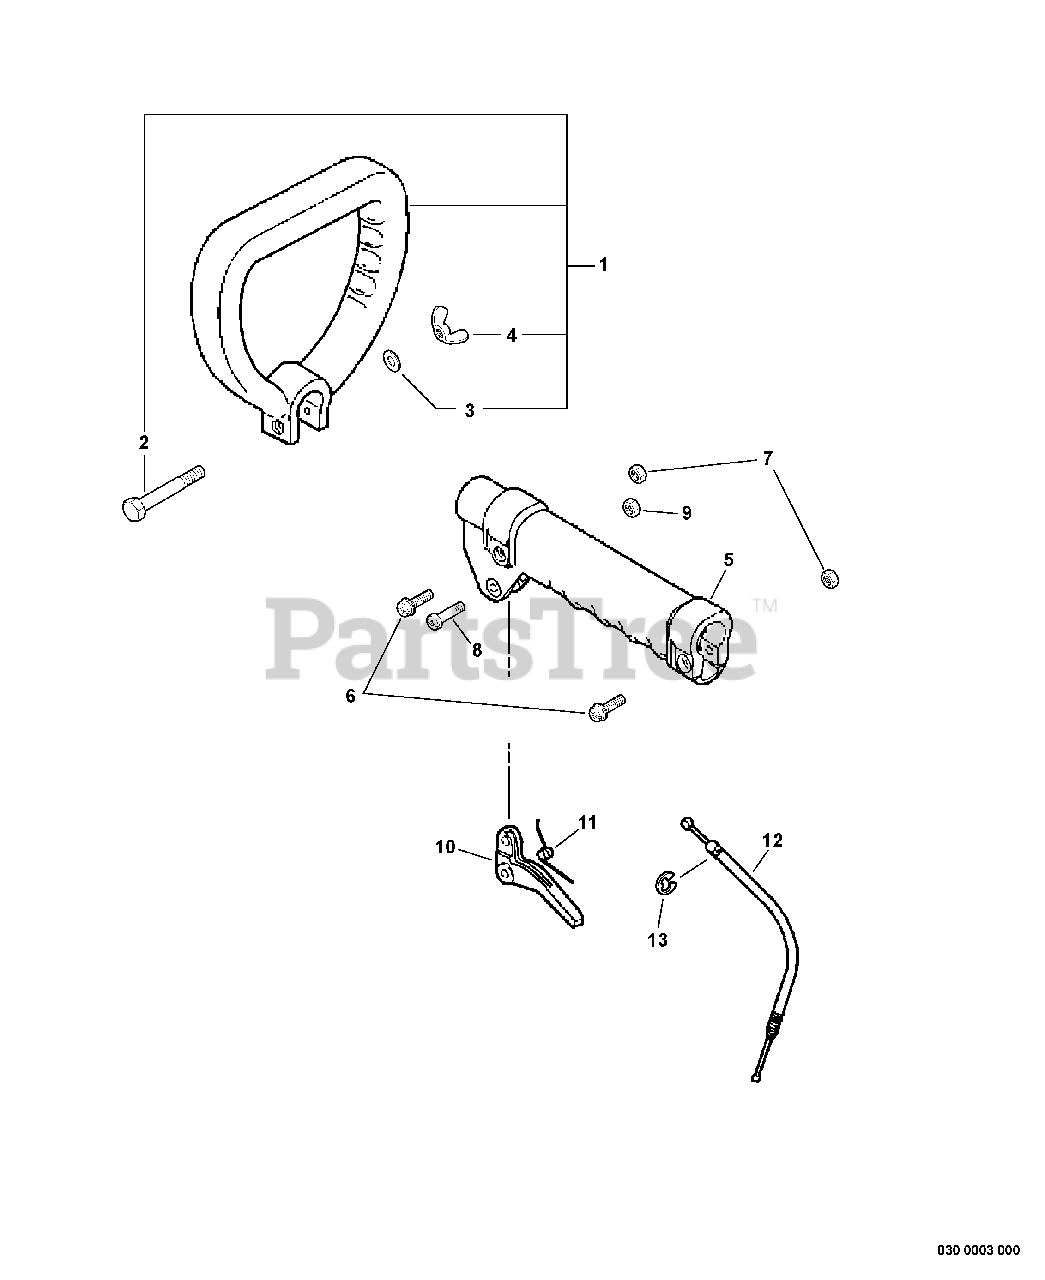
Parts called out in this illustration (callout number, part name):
1	HANDLE ASSY - FRONT
2	BOLT - 1/4-20 X 1-1/2"
3	WASHER - 1/4"
4	WINGNUT - 1/4-20
5	GRIP, HANDLE
6	SCREW - 5X25
8	SCREW - 5X30
9	LOCKNUT - 5
10	TRIGGER, THROTTLE
11	SPRING, TRIGGER
12	CABLE, THROTTLE
13	RING, RETAINING - 5
